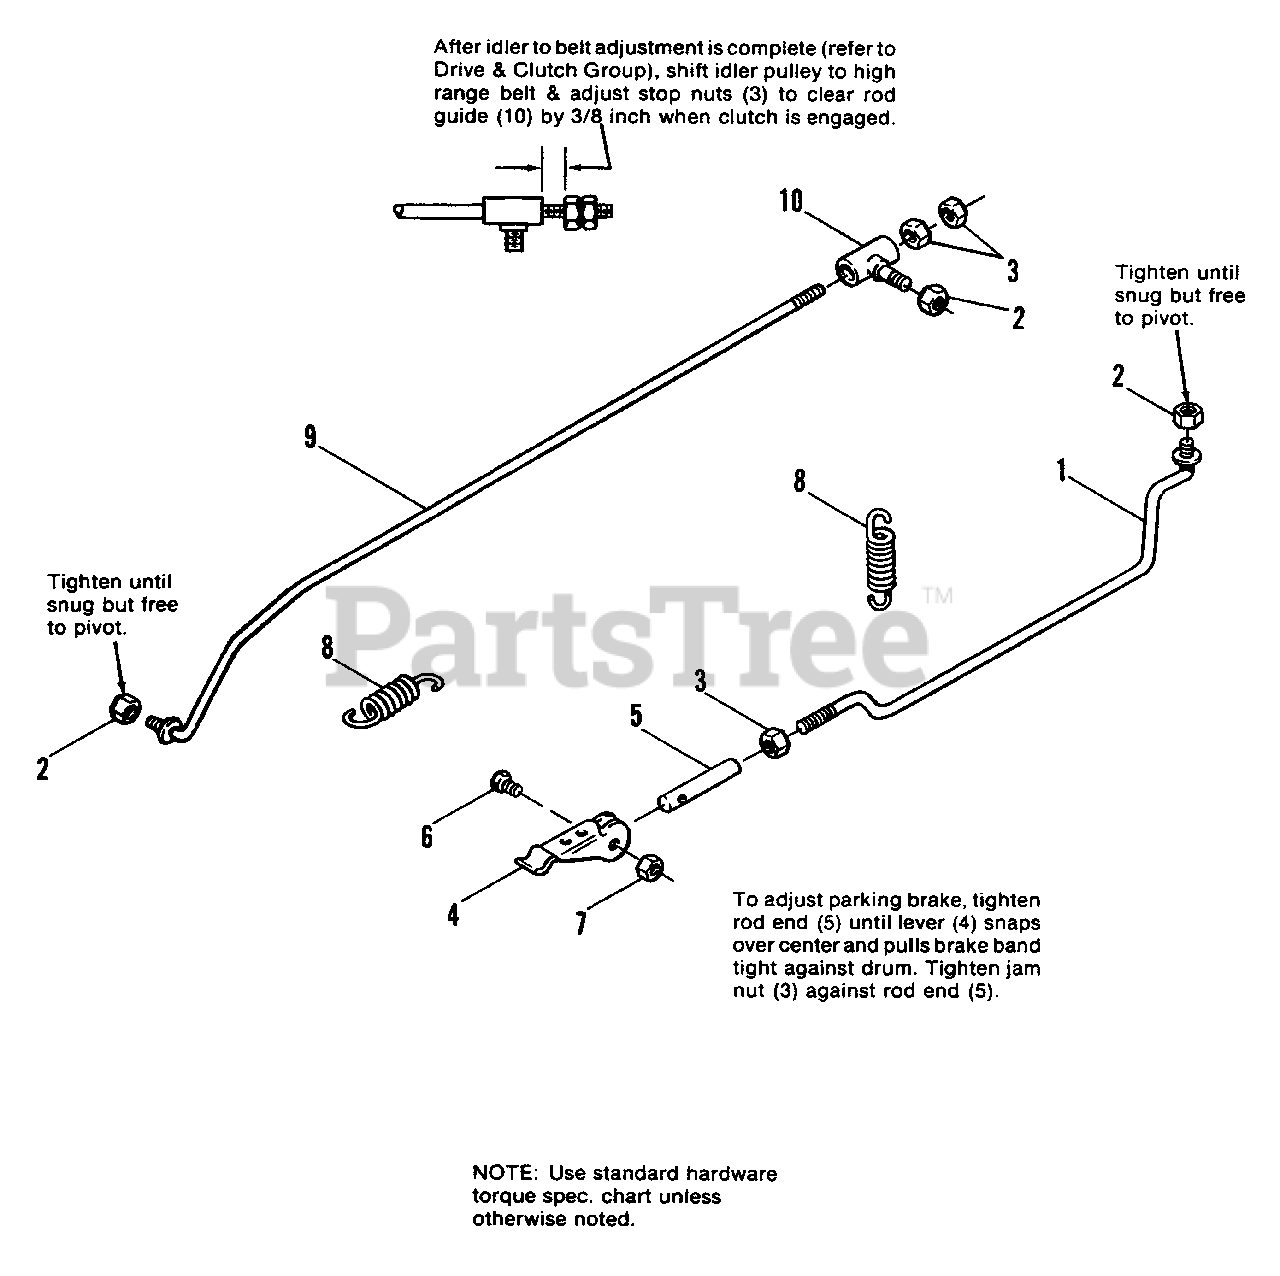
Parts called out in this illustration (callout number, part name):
1	PARKING BRAKE ROD ASSY.
2	LOCKNUT, Hex, 5/16-18
3	NUT, Hex, Full, 5/16-18
4	LEVER, Parking Brake
6	CAPSCREW, Hex Hd., 1/4-20 x 1
7	LOCKNUT, Hex, 1/4-20
9	CLUTCH & BRAKE ROD ASSY.
10	ROD GUIDE ASSY.
